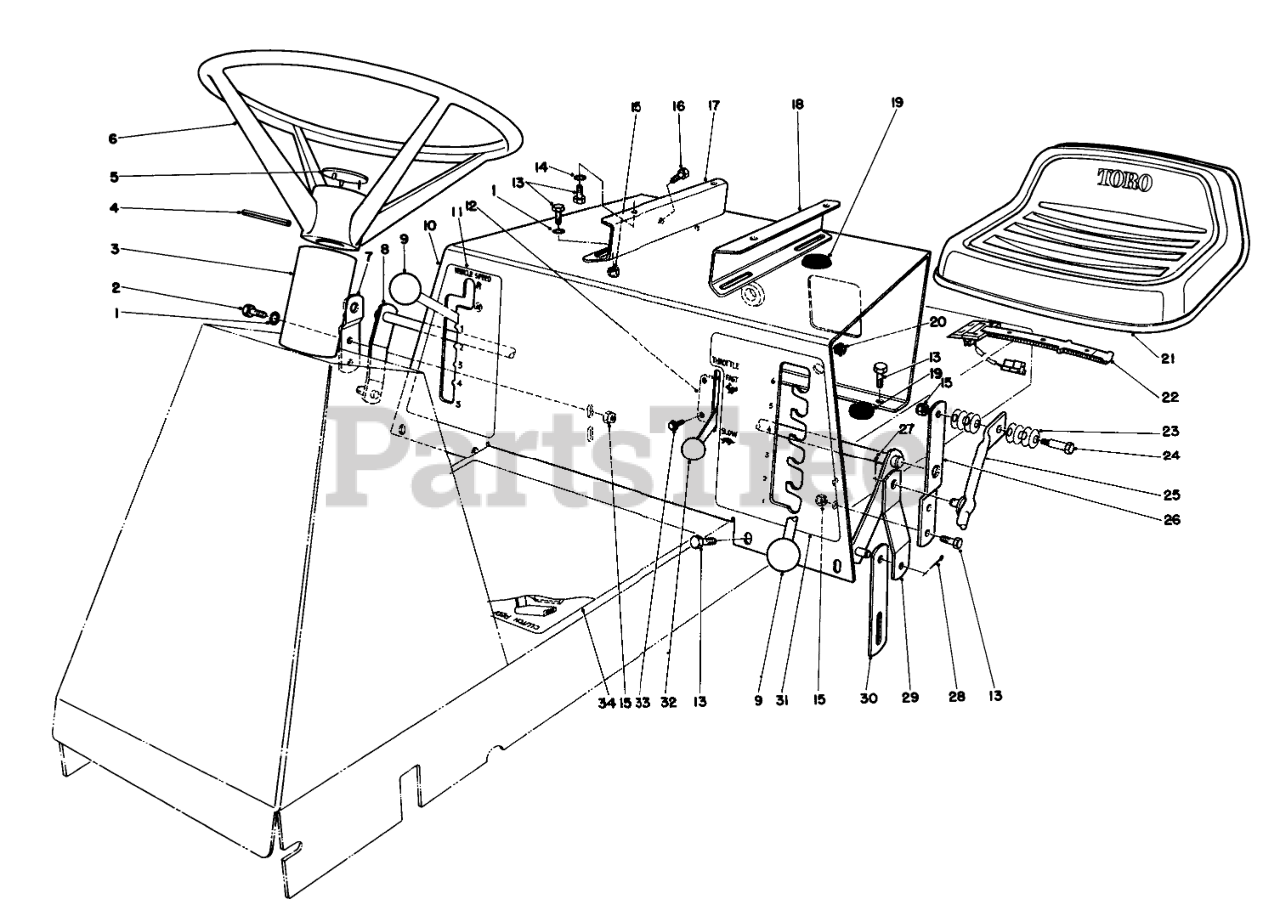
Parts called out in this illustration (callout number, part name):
1	WASHER-PLAIN
2	SCREW-HH
3	STRG. SHAFT COVER
4	PIN-ROLL
5	Cap-Steering Wheel
6	Wheel-Steering (Incl. Ref. #5)
7	Bracket H.O.C Support
8	HOC LEVER WA B
9	Knob
10	Support Seat
11	Decal-Transmission
12	Throttle Control (Incl. Ref. #32)
13	SCREW-HH
14	WASHER-LOCK
15	NUT-LOCK, NI
16	SCREW-HH
17	Bracket-Seat RH.
18	Bracket-Seat LH.
19	GROMMET
20	GROMMET
21	Seat
22	SWITCH-SEAT
23	WASHER-BELLEVILLE
24	BOLT-SHOULDER
25	HOC LEVER WA B
26	Bracket
27	PIN-COTTER
28	PIN-COTTER
29	Bracket-Height Of Cut Engagement
30	Link-Deck Suspension
31	Decal-Height Of Cut
32	KNOB-CONTROL
33	SCREW-HWHTF
34	INSTRUCTION DECAL
